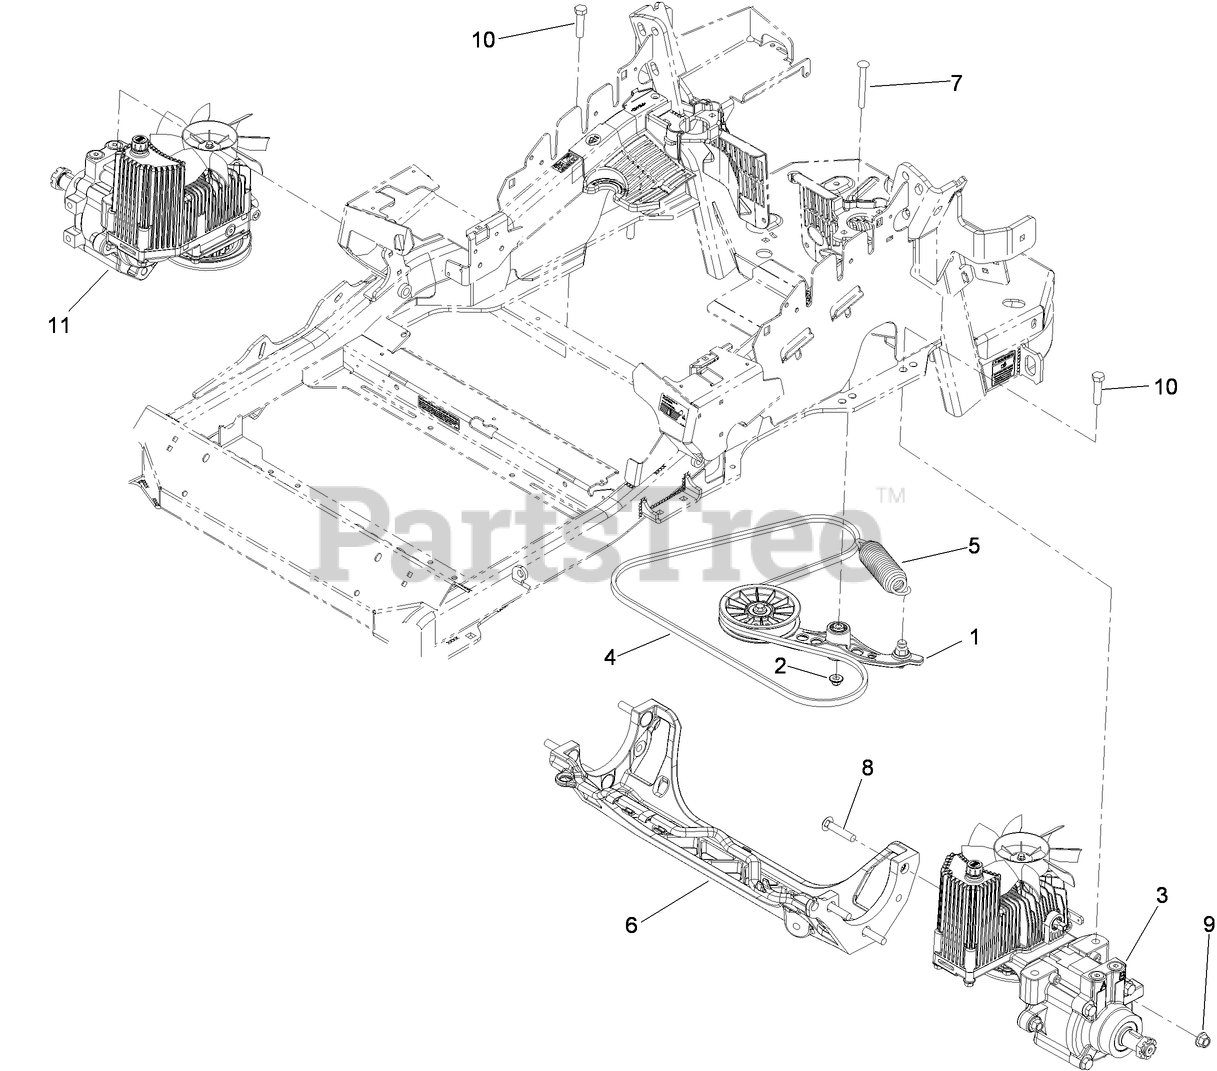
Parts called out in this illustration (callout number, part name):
1	PUMP IDLER ASM
2	NUT-FLANGE, NI
3	LH HYDRO ASM (16cc W/SHOCK)
4	BELT
5	EXTENSION-SPRING
6	CRADLE-HYDRO
7	BOLT-CARRIAGE
8	SCREW-CARR
9	NUT-LOCK
10	SCREW-HH
11	RH HYDRO ASM (16cc W/SHOCK)
